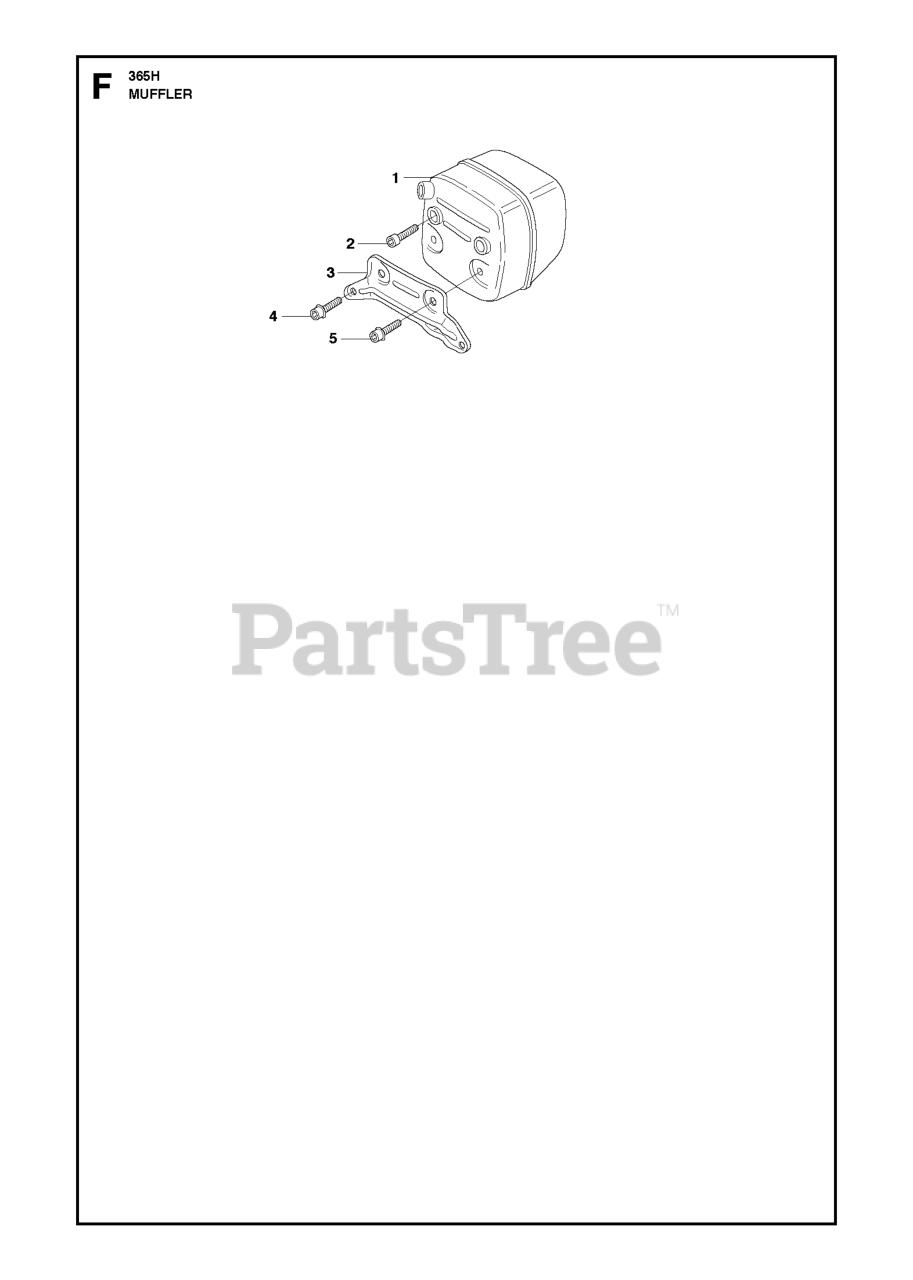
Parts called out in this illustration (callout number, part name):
1	MUFFLER ASSY
2	SCREW MC6S 6X20
3	RP SUPPORT
4	SCREW IHSCFM
5	SCREW IHSCFM
